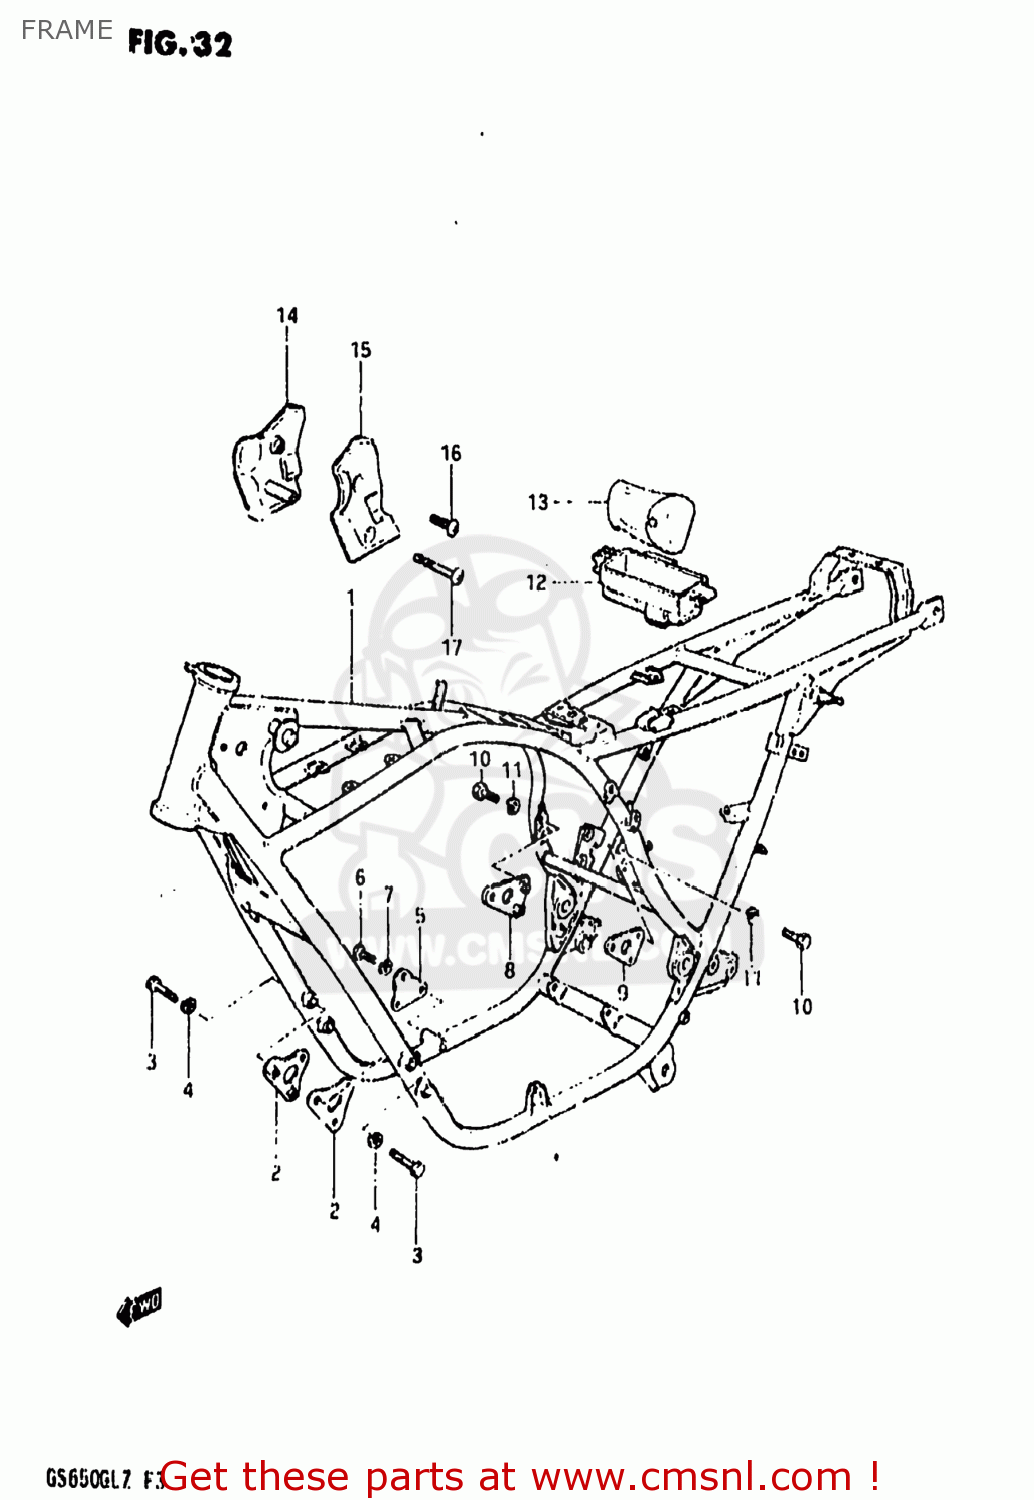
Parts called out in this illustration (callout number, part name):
1	FRAME
2	PLATE,ENGINE MOUNTING NO
3	BOLT
4	LOCK WASHER
5	BOLT,CRANKCASE ADJUST
6	BOLT
7	LOCK WASHER
8	PLATE,ENGINE MOUNTING NO
9	PLATE,ENGINE MOUNTING
10	BOLT
11	LOCK WASHER
12	HOLDER,TOOL
13	TOOL SET
14	COVER,FRAME HEAD,RIGHT
15	COVER,FRAME HEAD,LEFT
16	(5X20) CROSS SCREW
17	SCREW, LOWER
